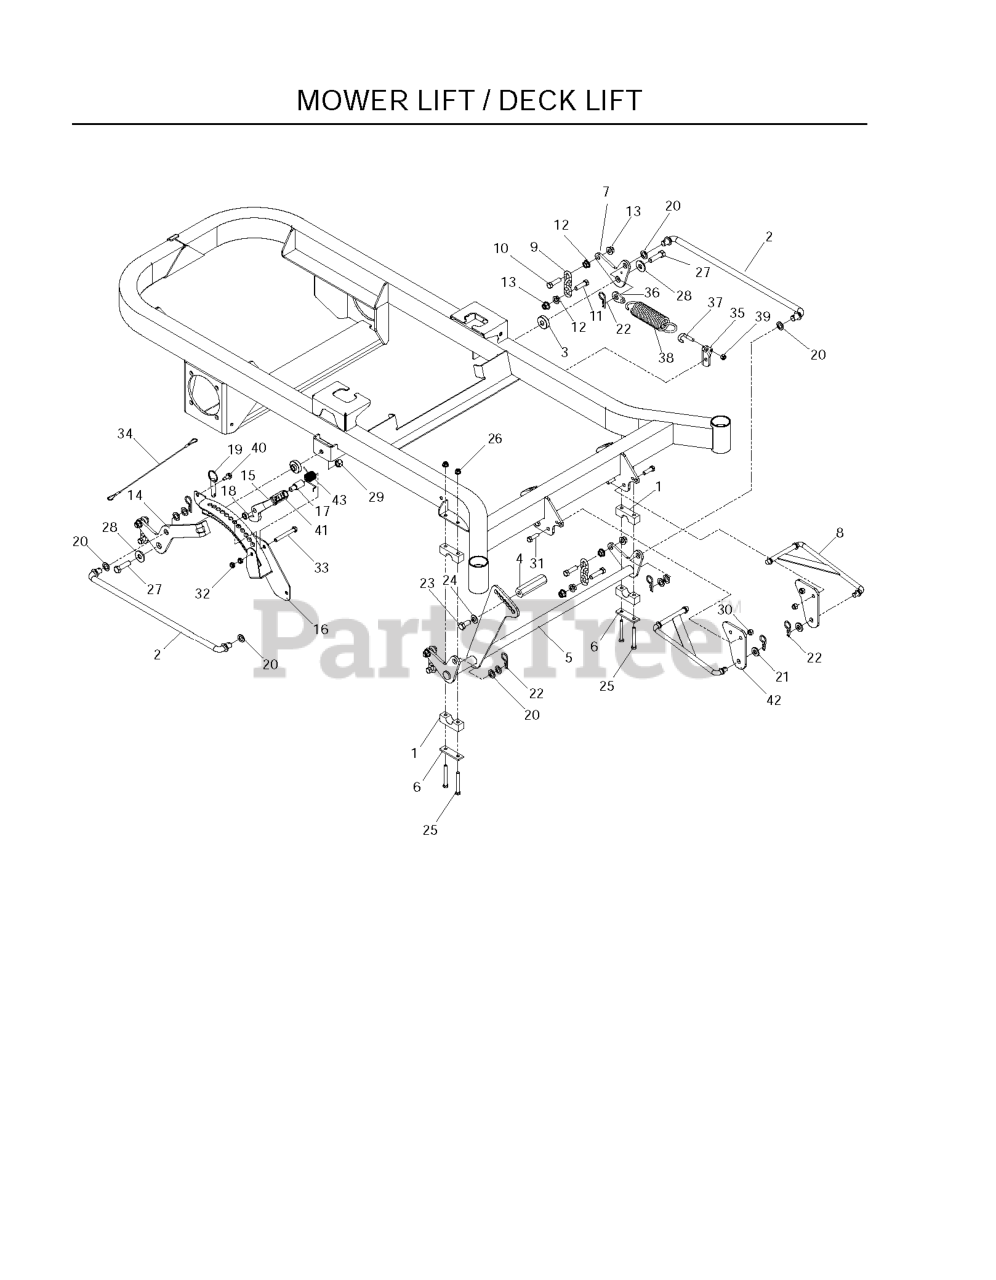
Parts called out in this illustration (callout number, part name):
1	PILLOW BLOCK
2	CROSS LINK
3	IDLER SPACER
4	PEDAL, FOOT, HEX
5	SHAFT, FRONT-LIFT
6	REINFORCEMENT BAR
7	BELLCRANK, RR, LIFT
8	STRUT LINKAGE
9	LIFT CHAIN - 3 LINK
10	HCS 7/16C X 1 1/2
11	HCS 7/16 - 14 X 1 3/4
12	NUT 7/16C WHIZ
13	NUT 7/16-14 HEX WHIZ LK
14	BELLCRANK, RR, RT
15	LATCH, TRANSPORT
16	HEIGHT, ADJUST, DECK
17	PIVOT, LATCH, TRANSPORT
18	SPACER, .3
19	PIN, 1/2 X 1 1/2, DETENT RING
21	WASHER 1/2" FLAT
22	PIN, COTTER 1 3/4
23	HHCS 1/2-13 X 1
24	WASHER, 7/16 DISC SPRING
25	HCS 5/16C X 2-3/4
26	5/16-18 NYLOC FLANGE NUT
27	HCS 1/2-13 X 1 3/4 GR 8
28	WASH USS FLAT 1/2
29	NUT 1/2-13 HEX NYLOC ZD
30	NUT 3/8-16 NYLOC
31	HCS 3/8C X 1 1/4 GR5
32	NUT HEX 3/8-16 NYLON, THIN
33	HCS 3/8C X 3
35	MOUNT, SPRING
36	TAB, SPRING
39	NUT 5/16 NYLOC
40	BOLT 5/16-18 X 3/4
41	GRIP, TRANSPORT-RELEASE
42	MOUNT, STRUT
43	SPRING, TORSION
